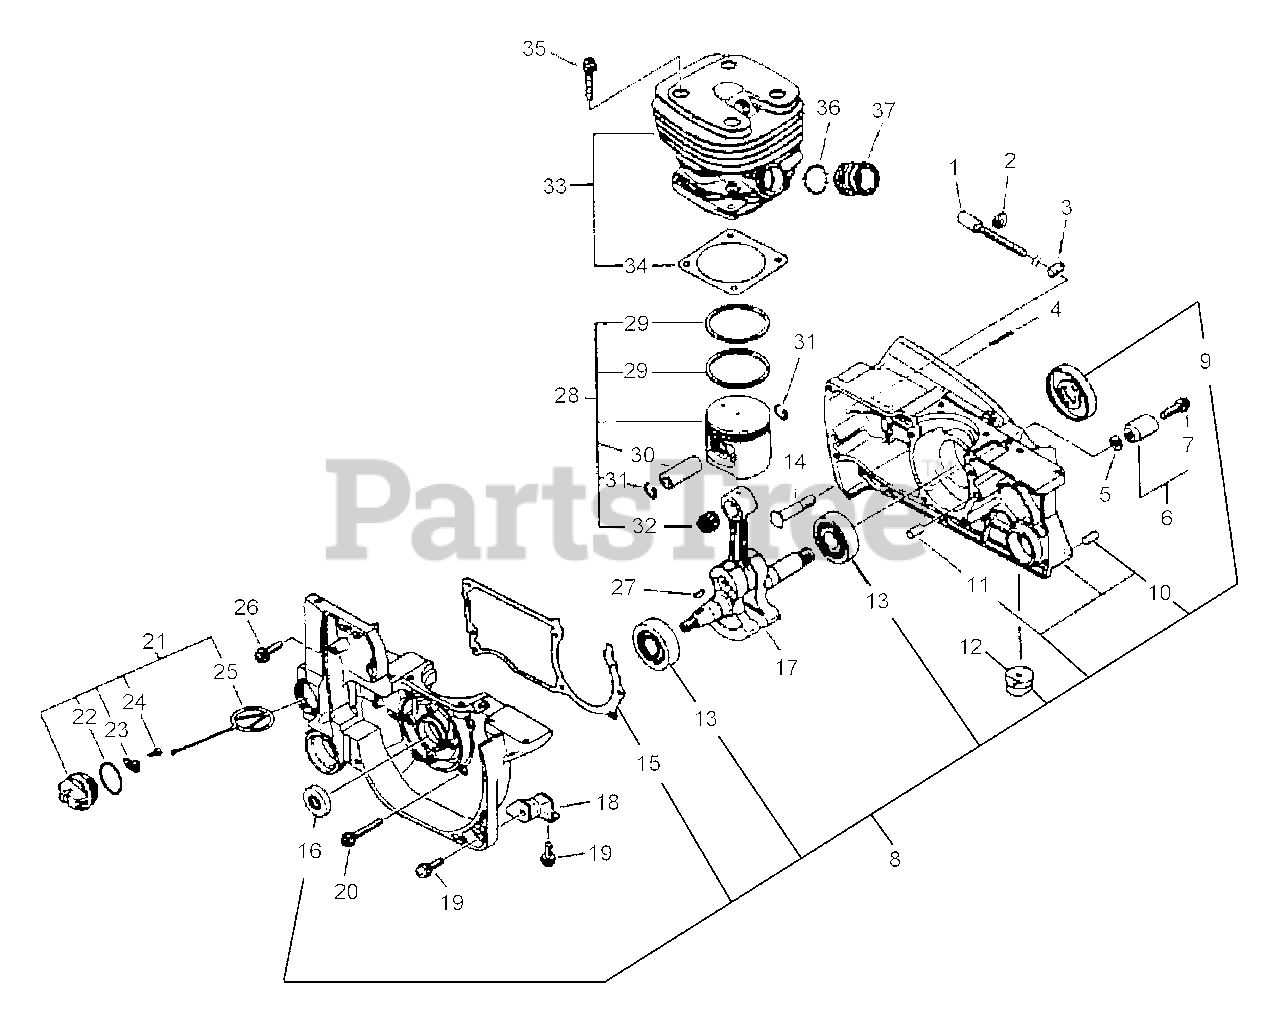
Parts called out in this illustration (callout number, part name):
1	SCREW, TENSIONER
3	TENSIONER, CHAIN
4	VENT, TANK
5	WASHER - 5
6	CHAIN CATCHER KIT
7	SCREW - 5X20
8	CRANKCASE KIT - GRAY
9	SEAL, OIL
10	PIN - SPRING -- 5X10
11	PIN - LOCATING
13	BEARING, BALL - 6203
14	STUD, GUIDE BAR
15	GASKET, CRANKCASE
16	SEAL, OIL
17	CRANKSHAFT ASSY
19	SCREW - 5X14
20	SCREW - 5X35
21	CAP ASSY - ORANGE
22	O-RING - 25
23	CONNECTOR, CAP
24	SCREW - 3X8
25	CONNECTOR, CAP
26	SCREW - 5X20
28	PISTON KIT
29	RING, PISTON
30	PIN, PISTON
31	RING, RETAINING
32	BEARING, NEEDLE
33	CYLINDER KIT
34	GASKET, CYLINDER
35	SCREW - 6X25
37	ADAPTOR, INTAKE
